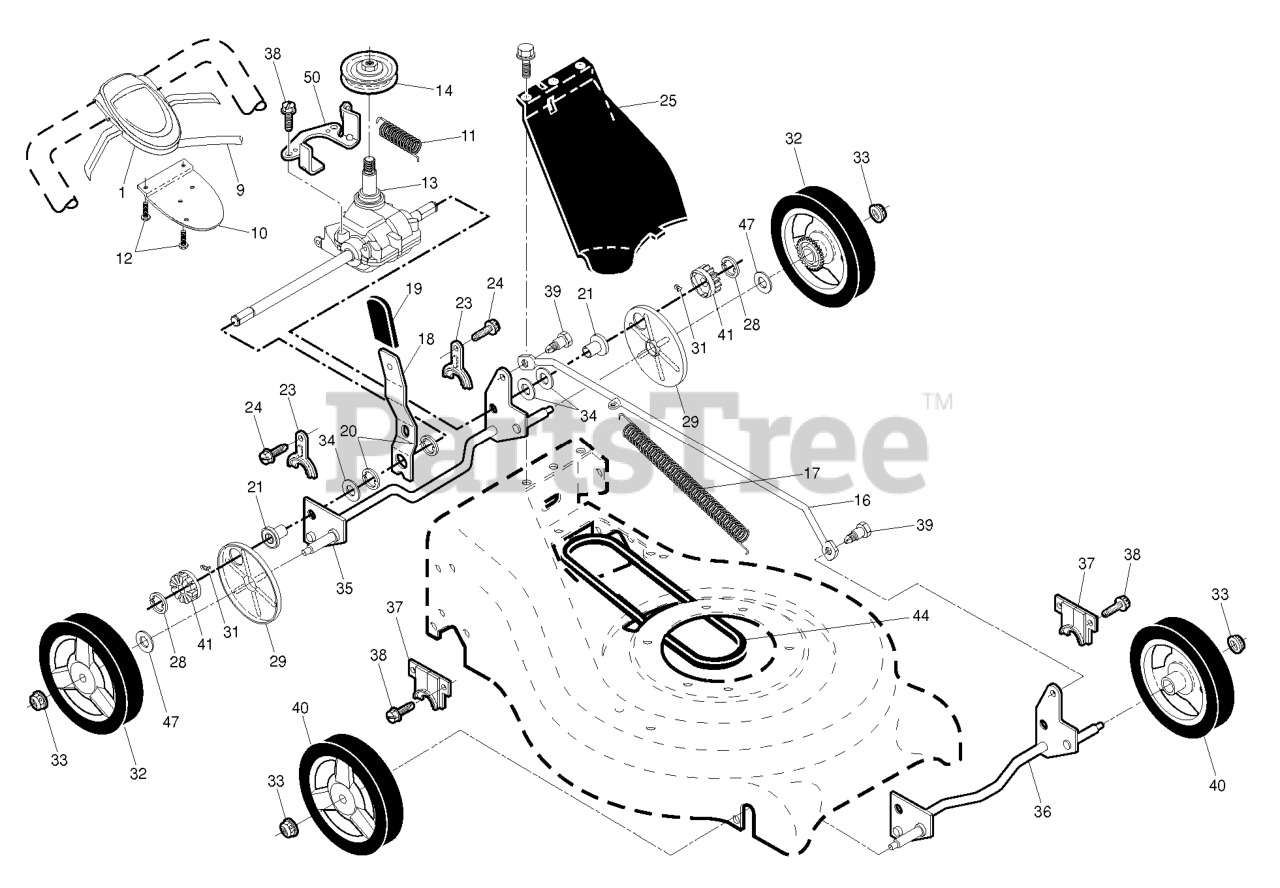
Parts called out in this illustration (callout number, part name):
1	NUT 5/16C CENTERLOCK
2	HCS 5/16C X 1 3/4
3	SPACER .70"
4	KEY 1/4 SQ X 1.0
6	SPACER .508"
8	7/16 LOCKWASHER
9	BOLT 7/16F X 2 1/2
10	CLUTCH TIE DOWN
11	MUFFLER GUARD, PAINT
12	KOH PIGTAIL
13	MUFFLER KOH
14	MUFFLER MT, PAINT
15	ENGINE MOUNT
16	ENGINE MOUNT
17	HCS 5/16C X 3/4
18	WASHER 5/16 FLAT
19	HCS 1/2C X 3 1/4
20	NUT 1/2-13 HEX NYLOC ZD
21	ISOLATOR WASHER
23	CABLE POSITIVE
25	HCS 1/4C X 5/8
26	NUT 1/4C CENTER LOCK
27	ISOLATOR SPACER
28	90 DEG.ELBOW 3/8NPT
29	PIPE 3/8 NPT 1-1/2
30	TEMP GAUGE DATCON #100182
31	BRACKET-TEMP GAUGE
32	HCS 5/16-18X2
33	WASHER 1/4 INT TOOTH
34	GROUND WIRE (KAW)
35	OIL DRAIN HOSE (KAW)
37	HCS 1/4C X 3/4 HCS
539101362	OIL DRAIN HOSE
539104415	KAW PIGTAIL
539104957	MUFFLER KAW.
